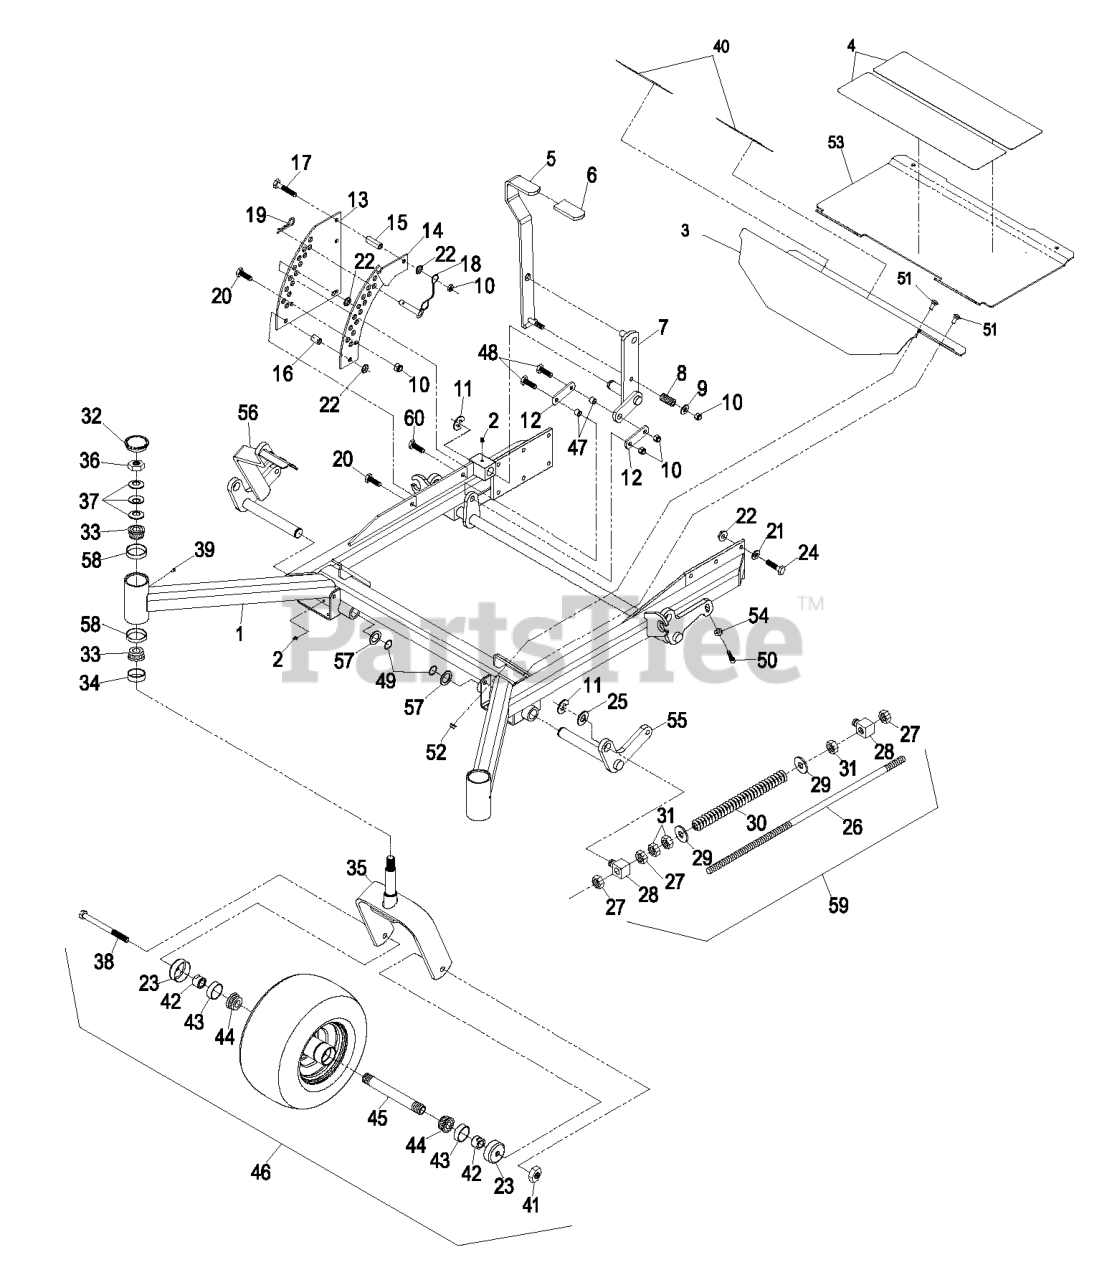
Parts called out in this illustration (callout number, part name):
1	KIT,FRONT FRAME XP 60
2	FITTING-GREASE
4	PAD-ANTISKID
5	LIFT LEVER/GRIP ASM
6	GRIP-LEVER, LIFT
7	ARM-LIFT, DECK
8	SPRING-COMPRESSION
9	WASHER-FLAT
10	NUT-LOCK, NI
11	RING-RETAINING, EXT
12	ARM-LIFT, DECK
13	PLATE-LIFT, DECK
14	PLATE-LIFT, DECK
15	BUSHING-LEVER, LIFT
16	BUSHING-LEVER, LIFT
17	SCREW-HH
18	PIN-HITCH (W/LANYARD)
19	PIN-COTTER
20	SCREW-HH
21	WASHER-BELLEVILLE
22	NUT-HHF, WHIZ
23	GUARD-SEAL
24	SCREW-HH
25	WASHER-FLAT
26	ROD-LIFT, DECK
27	NUT-HEX
28	SWIVEL-DECK MOUNT, REAR
29	WASHER-FLAT
30	SPRING-SUPPORT, DECK
31	NUT-JAM
32	CAP-GREASE
33	Cone-Bearing Tapered Roller
34	SEAL-GREASE
36	NUT-LOCK, NI
37	WASHER-BELLVILLE
38	SCREW-HH
40	PAD-ANTI SKID
41	NUT-LOCK, NI
42	SPACER-NUT
43	SEAL-CASTER
44	BEARING-CONE, TAPERED ROLLER
47	BUSHING
48	SCREW-HH
49	RING-RETAINING
50	SCREW-HSH
51	BOLT-CARR
53	ASM,LIFTOUT FLOORPAN/PAD
54	NUT-JAM
55	WLD, FRONT LIFT SHAFT - L
56	WLD, FRONT LIFT W/ LEVER
57	WASHER-SPACER
58	CUP-BEARING
59	FRONT FRAME SPRING ASM
60	SCREW-HH
